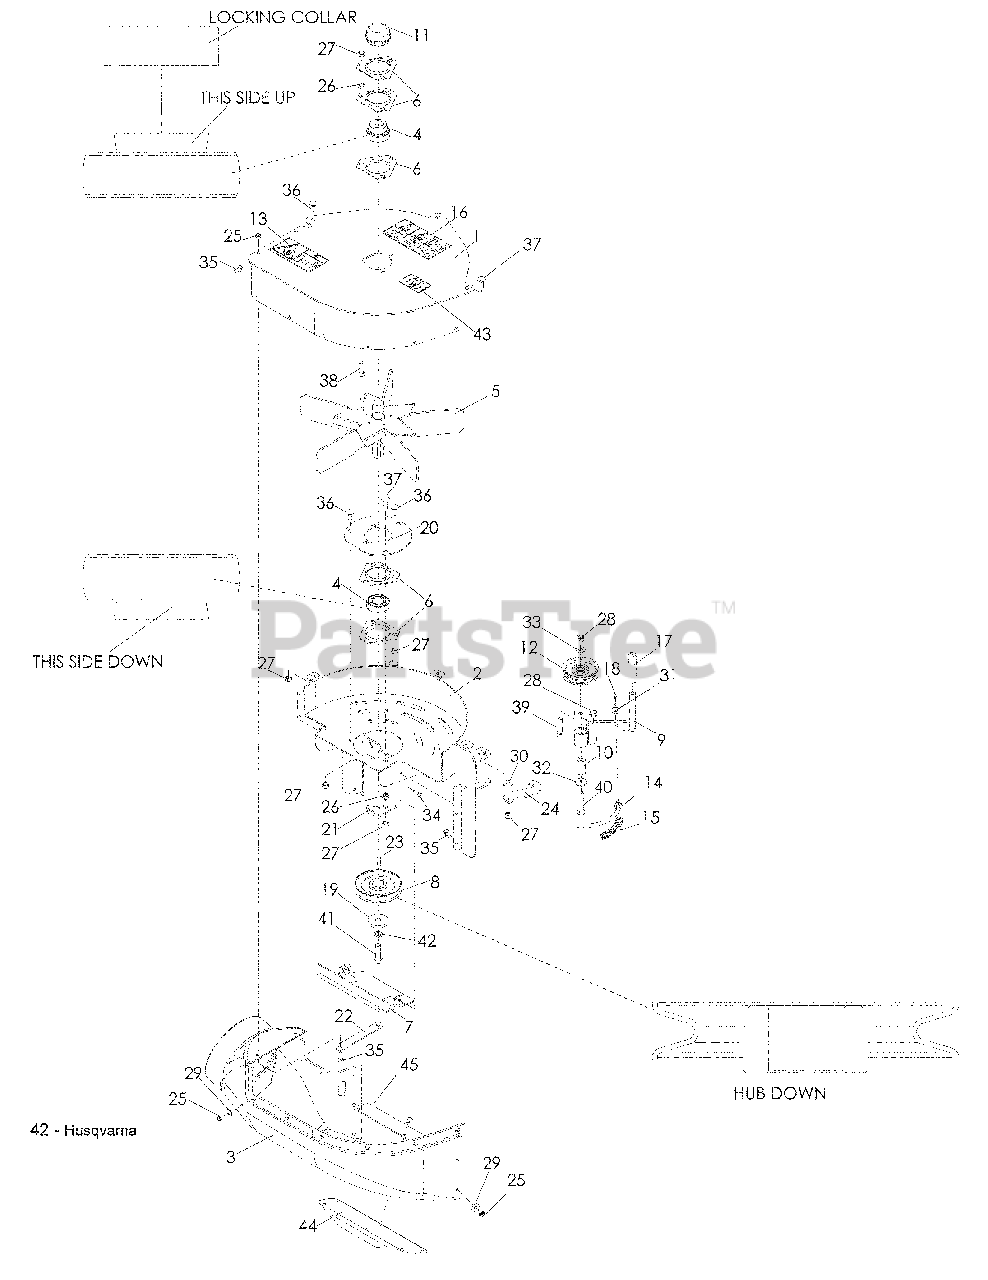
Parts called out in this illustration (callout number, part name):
1	FAN COVER W/DECALS
2	BLOWER HOUSING
3	LOWER HOUSING
7	COVER PLATE
8	SHEAVE, 4"
10	SLEEVE BUSHING
11	CAP, GREASE
13	DECAL, SEVERING
14	SPRING ROD
16	DECAL, WARNING
17	GRIP, VINYL
18	PIN, COTTER 3/32 x ¾
19	HEAVY WASHER
20	BEARING PLATE
21	BELT GUIDE
23	KEY ¼ SQ x ¾
24	IDLER ARM KEEPER
25	NUT ¼-20, THIN, NYLOC
26	NUT 5/16-18
27	NUT 5/16-18 HEX NYLOC
28	NUT 3/8-16 CENTERLOCK
30	WASHER 5/16 STD FLT
31	WASHER 5/16 SAE
32	WASHER 3/8 STD FLT
33	WASHER 3/8 SAE FLT
34	SCREW, ¼-20 x 5/8 BTN
35	RHSNB ¼-20 x ¾ GR2
36	RHSNB 5/16-18 x ¾
37	RHSNB 5/16-18 x 1
38	RHSNB 5/16-18 x 1¼
39	HCS 3/8-16 x 1½
40	HCS 3/8-16 x 2
41	HCS 7/16-20 x 1½
42	LOCKWASHER 7/16
43	DECAL, NO STEP
44	BLOWER SUPPORT
45	PLATE, BLOWOUT
